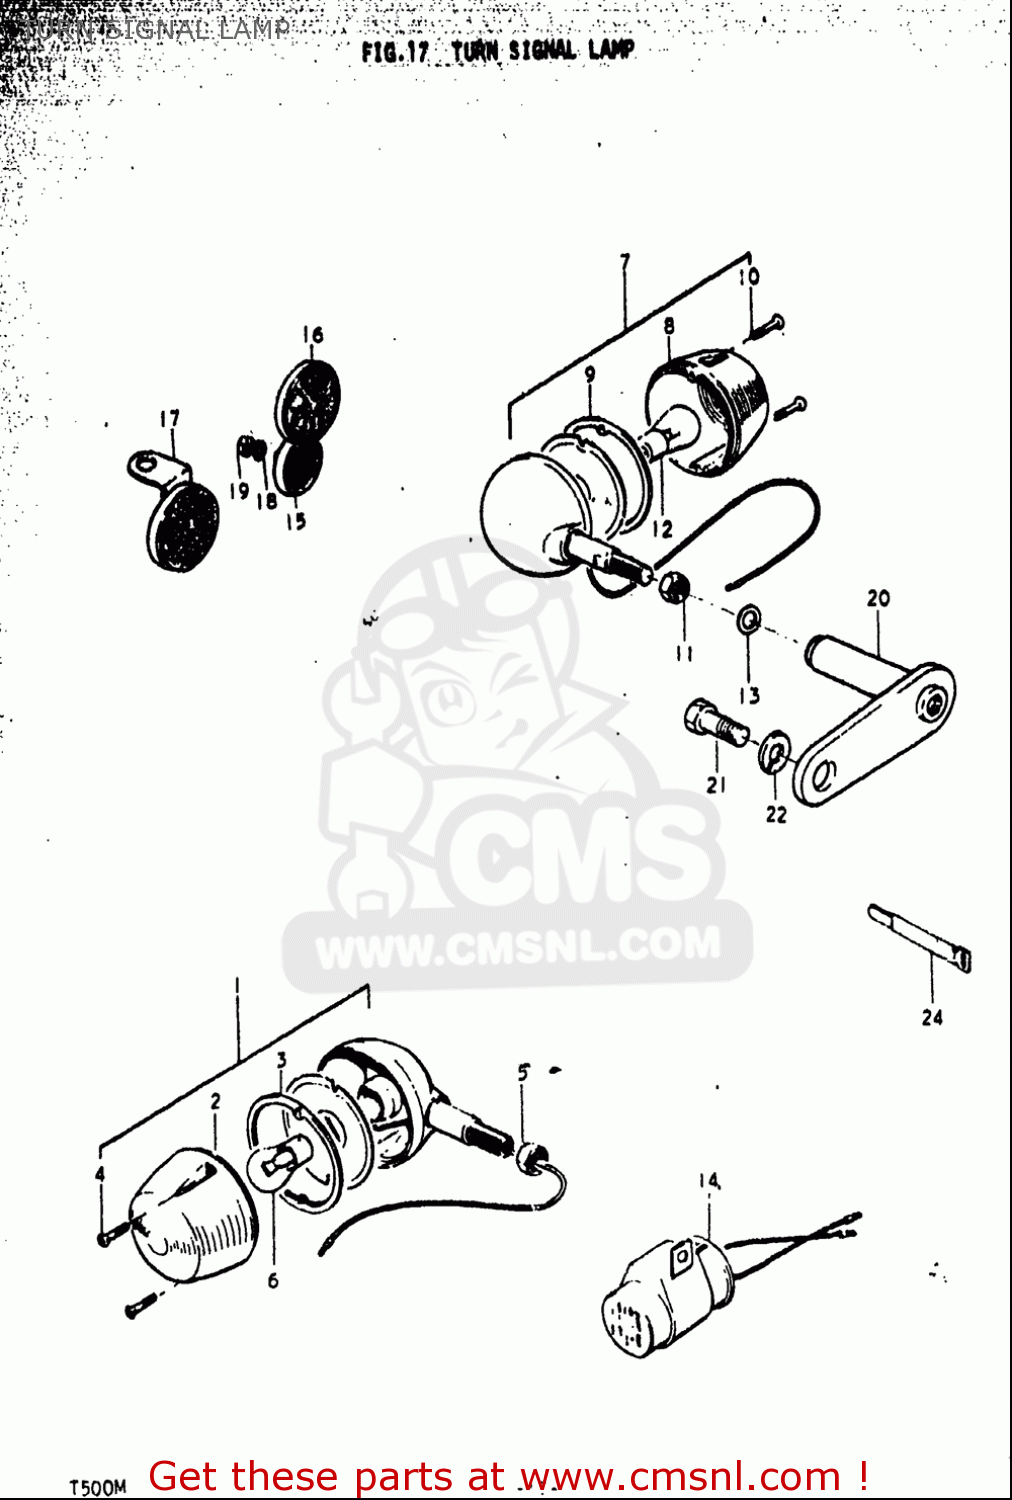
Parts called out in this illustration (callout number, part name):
1	LAMP ASSY,FR TURN SIGNAL
2	LENS,TURNSIGNAL
3	GASKET,TURNSIGNAL LENS (NAS)
4	SCREW
5	NUT
6	BULB(12V23W,STANLEY,A4577A)
7	LAMP ASSY,RR TURNSIGNAL
8	LENS,TURNSIGNAL
9	GASKET,TURNSIGNAL LENS (NAS)
10	SCREW
11	NUT
12	BULB(12V23W,STANLEY,A4577A)
13	WASHER
14	RELAY,TURN SIGNAL
16	REFLEX REFLECTOR,RR
18	WASHER,LOCK
19	NUT
21	BOLT
22	WASHER,LOCK
24	CLAMP
